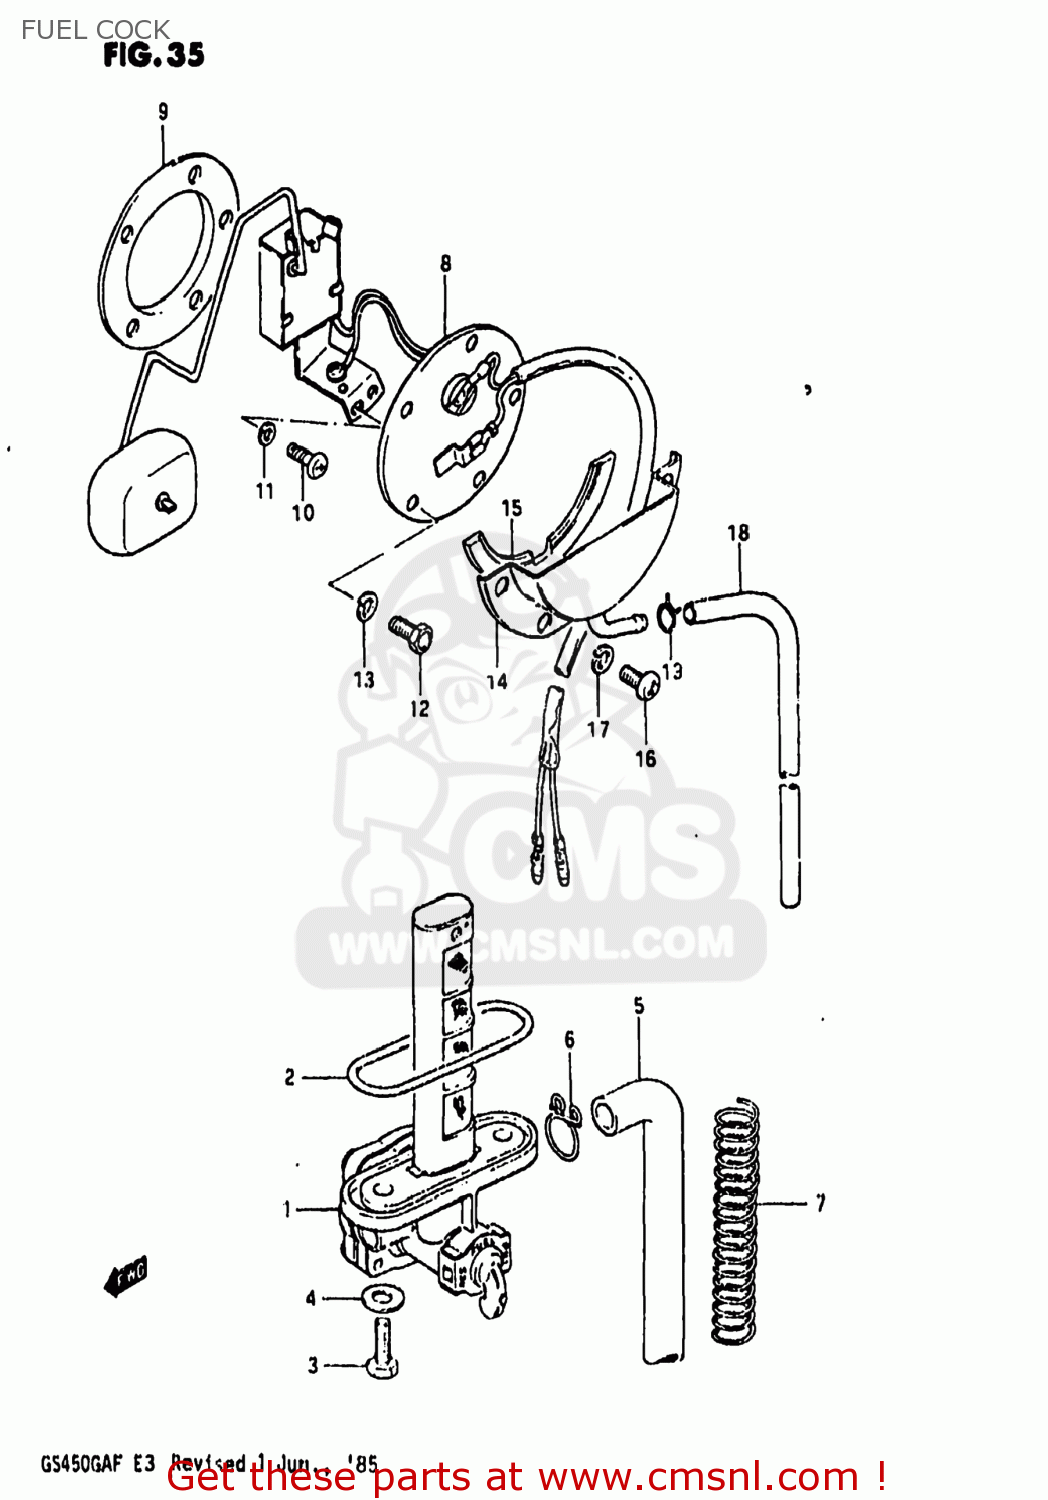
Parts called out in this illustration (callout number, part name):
1	COCK ASSY,FUEL
2	O RING
3	BOLT(6X20)
4	GASKET
5	HOSE
6	CLIP
7	SPRING
8	GAUGE ASSEMBLY,FUEL LEVEL
9	GASKET,FUEL LEVEL GAUGE (NAS)
10	SCREW 5X10
11	LOCK WASHER
12	BOLT 5X10
13	LOCK WASHER
14	PLATE,FUEL DRAIN
15	GASKET (NAS)
16	SCREW
17	LOCK WASHER
18	HOSE
19	CLIP
